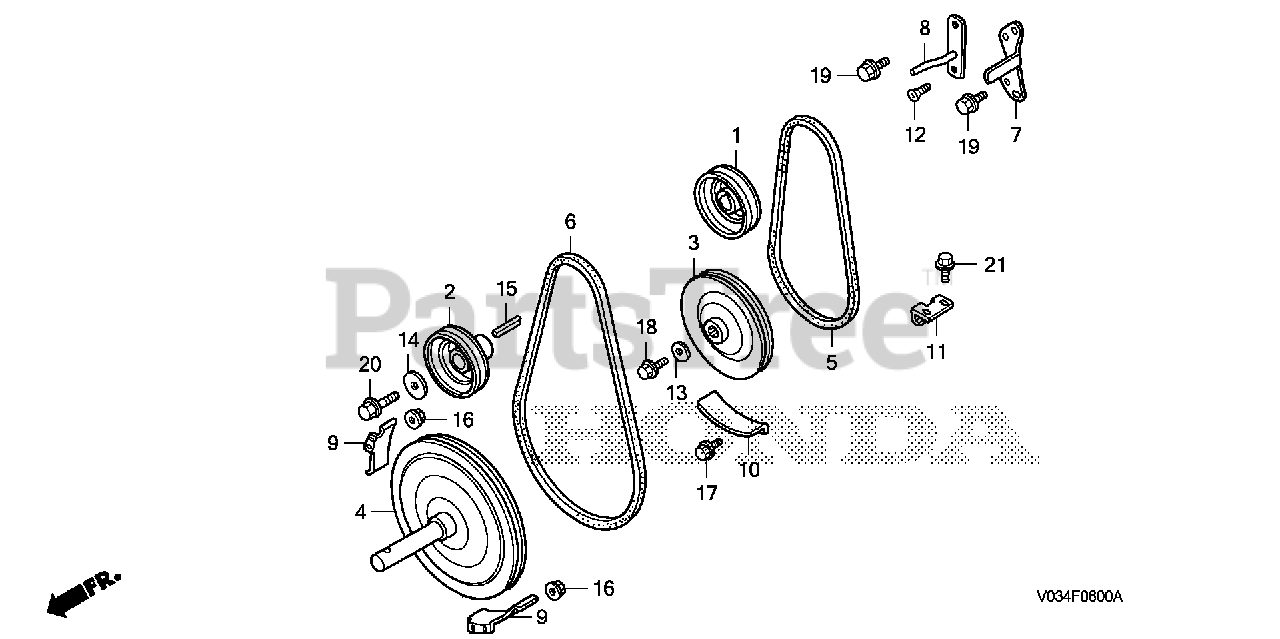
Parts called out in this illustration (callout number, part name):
1	PULLEY, WHEEL DRIVE
2	PULLEY, AUGER DRIVE
3	PULLEY, WHEEL DRIVEN (133MM)
4	PULLEY, AUGER DRIVEN (198MM)
5	V-BELT (SA-29)
6	V-BELT (SB-35)
7	STOPPER, R. BELT
8	STOPPER, L. BELT
9	STOPPER, AUGER BELT
10	PROTECTOR, BELT (WHEEL)
11	GUIDE, BELT
12	BOLT, LOCK STRIKER
13	WASHER, CAMSHAFT SIDE
14	WASHER, LOCK (8.5X35X4.5)
15	KEY (7X7X33) (OVER SIZE) (YELLOW)
16	NUT, FLANGE (6MM)
17	BOLT, FLANGE (6X12)
18	BOLT, FLANGE (6X16)
19	BOLT, FLANGE (8X16)
20	BOLT, FLANGE (8X28)
21	BOLT, FLANGE (6X12)
21	BOLT, FLANGE (6X14)
